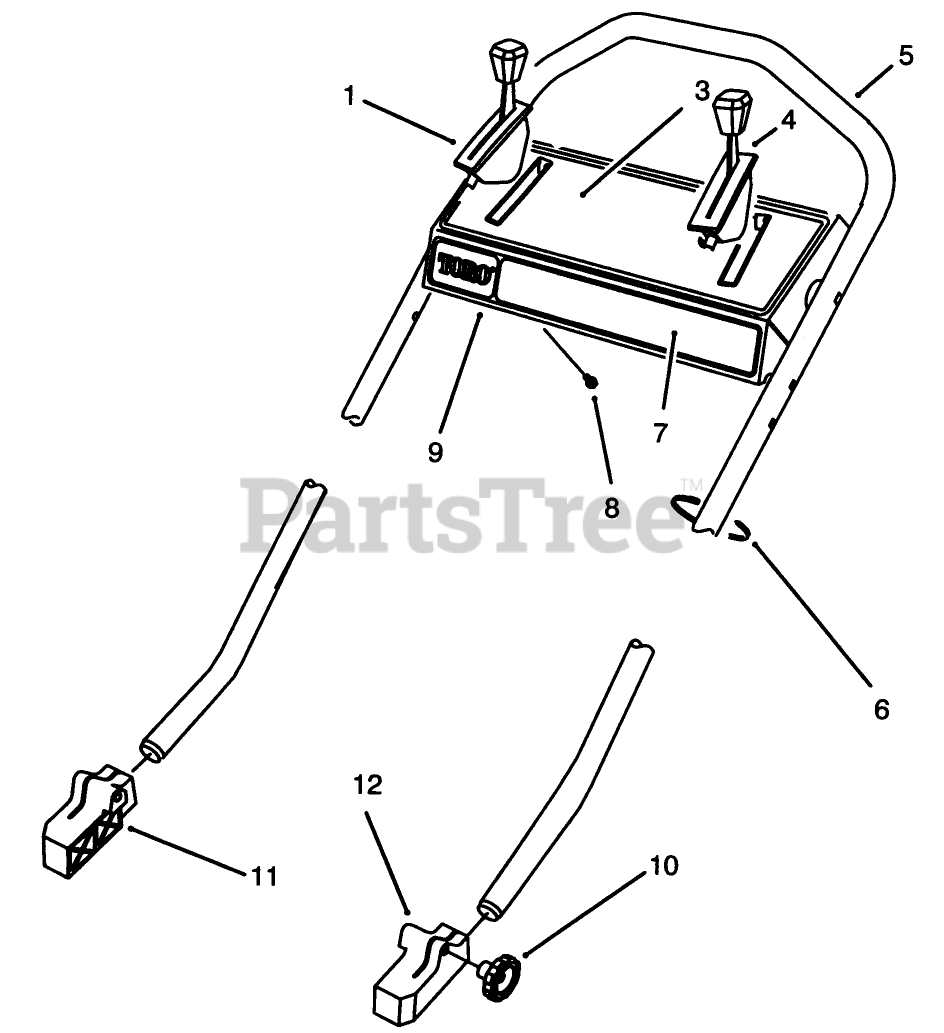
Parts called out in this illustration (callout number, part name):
1	CONTROL-SPEED, GROUND
3	DECAL - INSTRUCTION
4	CONTROL - THROTTLE
5	HANDLE - 53CM (DIPPED)
6	TIE-CABLE
7	DECAL-PANEL
8	SCREW-TAP
9	PANEL
11	MOUNT-HANDLE, RH
12	MOUNT-HANDLE, LH
